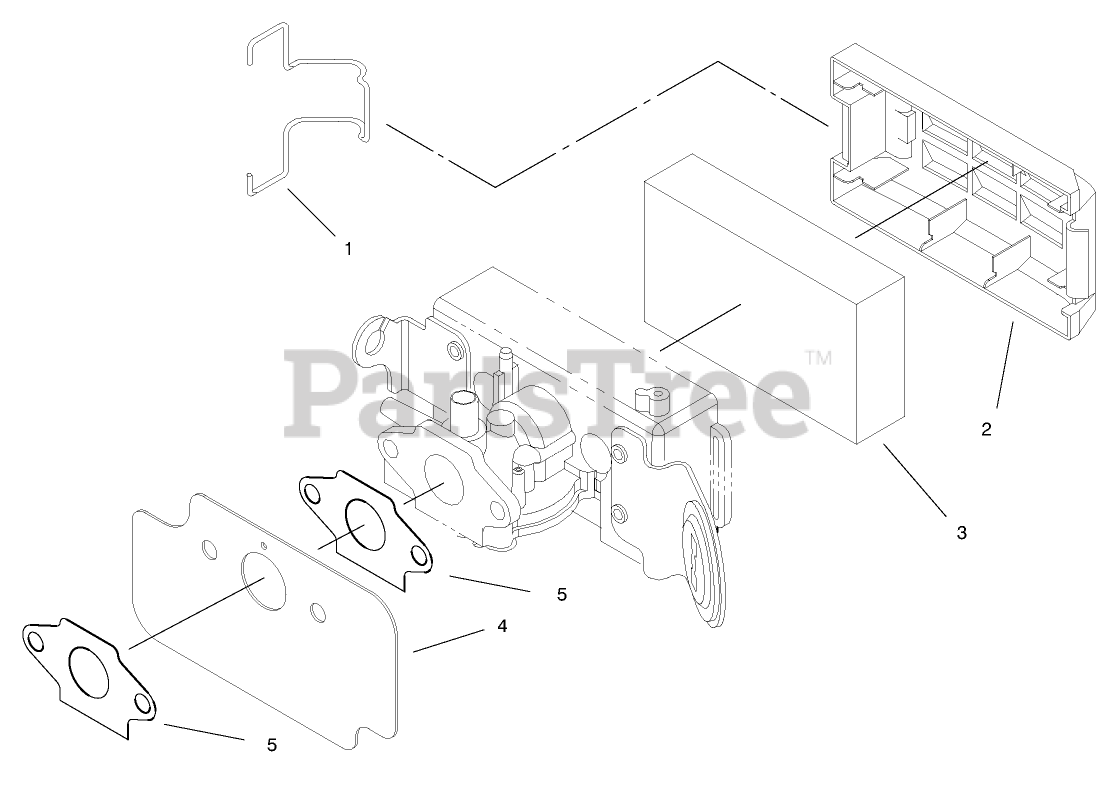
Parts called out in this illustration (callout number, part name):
1	RETAINER-COVER, FILTER
2	COVER-AIR FIL. V
3	ELEMENT-AIR FIL VF
4	SHIELD - CARB. VF
5	GASKET-CARB VF
